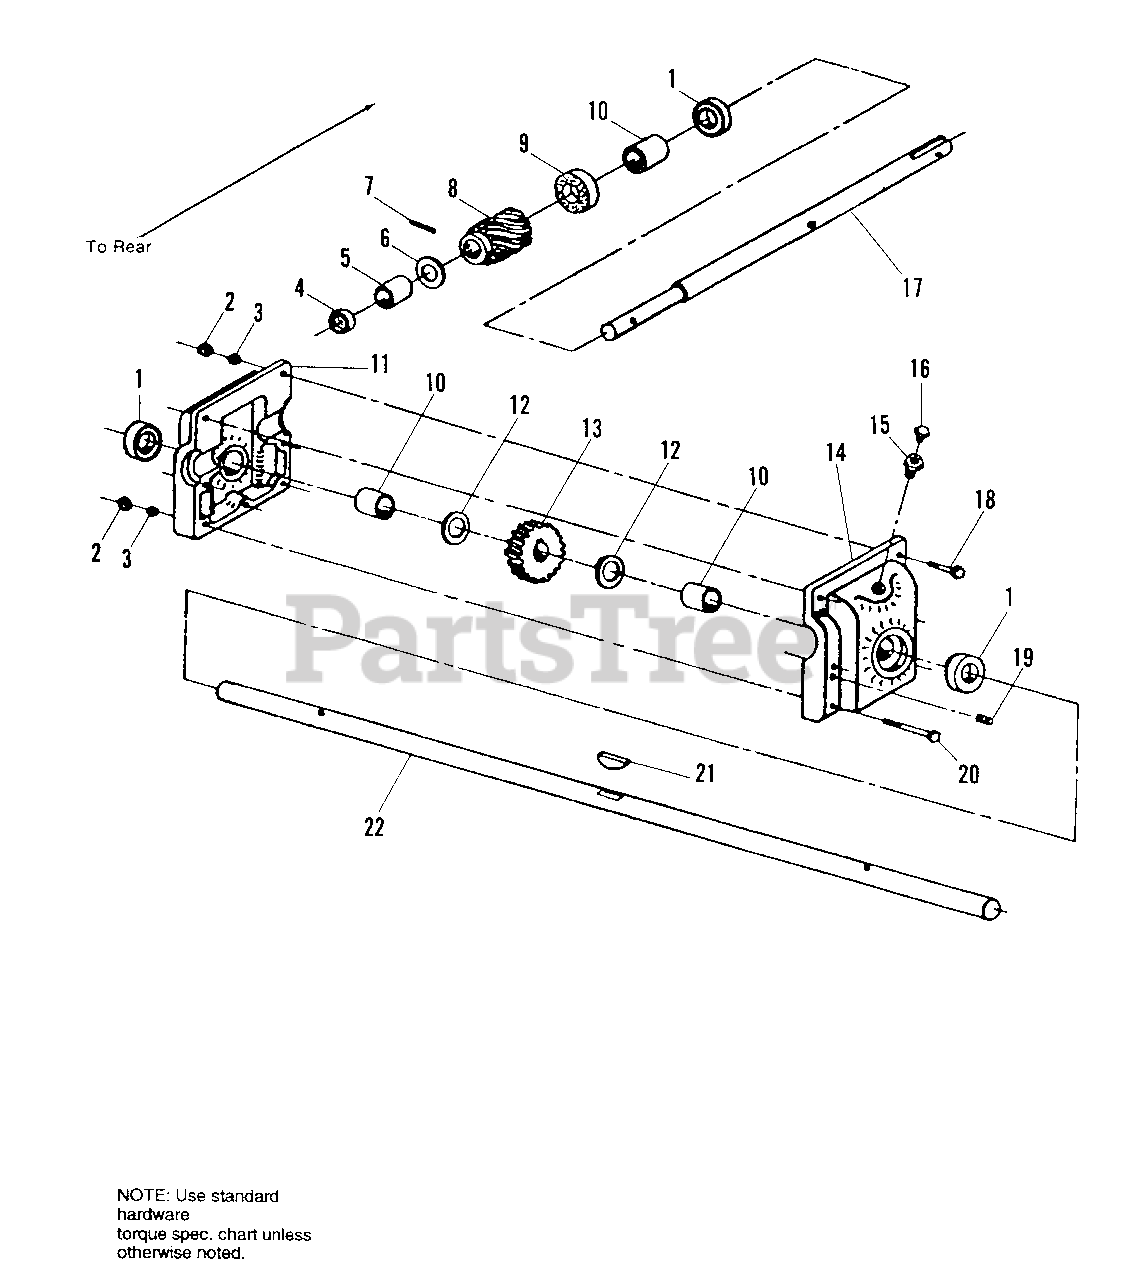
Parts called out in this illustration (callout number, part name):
1	SEAL, Oil (1 x 1-1/2 x 1/4)
1	SEAL, Oil (1 x 1-5/16 x 1/8)
2	NUT, Hex, 5/16-18
3	LOCKWASHER, 5/16
4	CAP Input
5	BUSHING, 7/8 x 1-1/8 x 1
5	BUSHING, 7/8 x 1-1/4 x 1
6	WASHER, 1-3/8
7	PIN, 1/4 x 1-3/8
8	WORM GEAR, R.H. Rotation
10	BUSHING, 1" I.D. x 1-1/4" O.D. x 1"
11	COVER, R.H.
12	WASHER, 1-1/2
13	GEAR, Brass
14	COVER, L.H.
15	FITTING Bushing, Reduction 7/8 x 1/8 NPT
16	BREATHER, 1/8 NPT
17	SHAFT, Input
18	CAPSCREW, Hex Hd., 5/16-18 x 1-1/4
19	PLUG, 1/8, NPT
20	CAPSCREW, Hex Hd., 5/16-18 x 2-1/4
21	KEY, Woodruff, 1/4 x 7/8
22	SHAFT, Output
